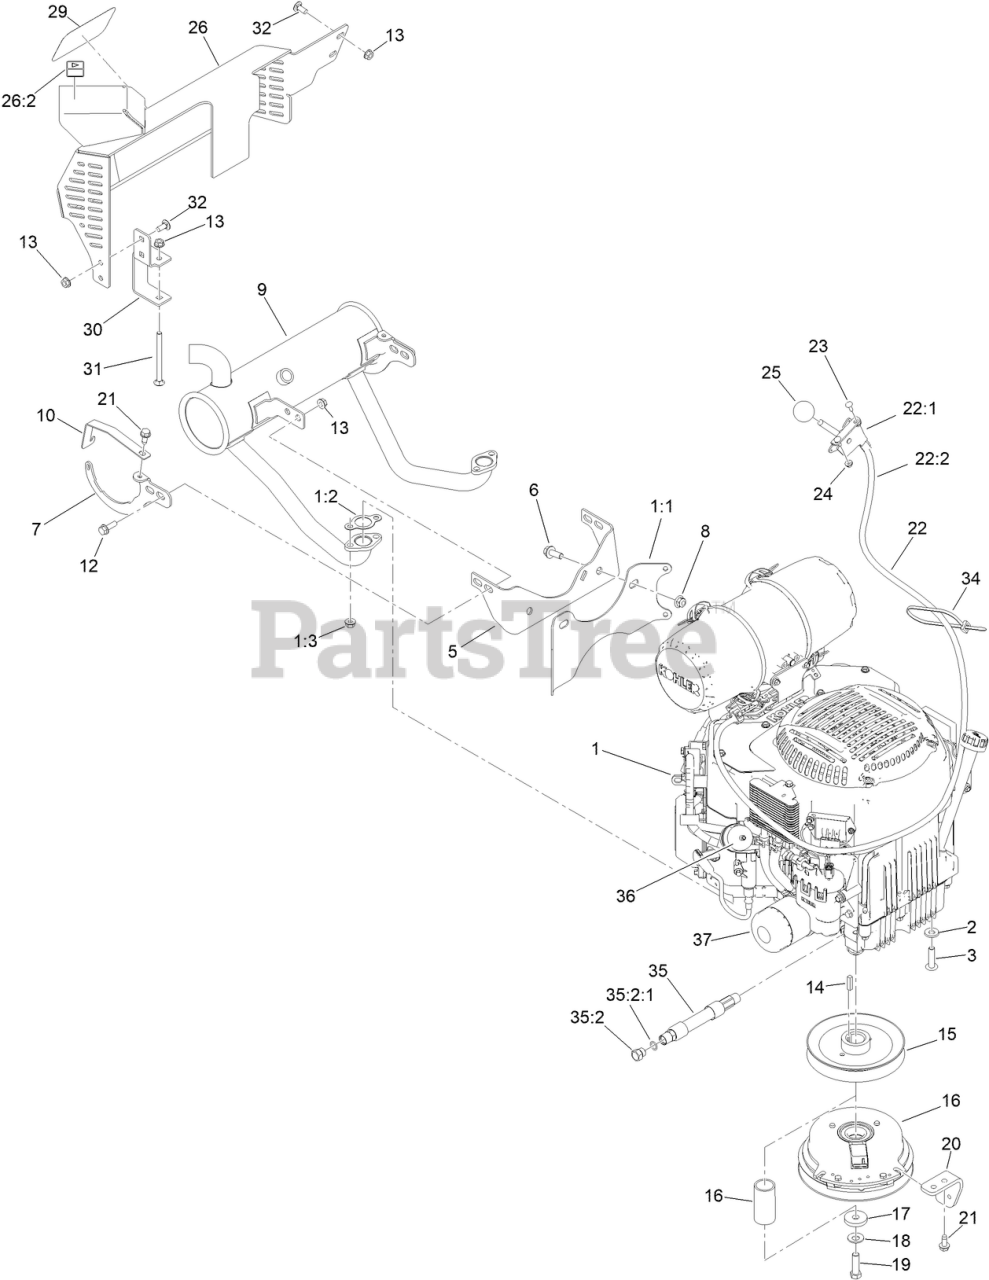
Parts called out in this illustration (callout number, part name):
1:1	BRACKET-MUFFLER
1:2	GASKET-EXHAUST
1:3	NUT-FLANGE
2	WASHER-BELLEVILLE
3	SCREW-BHTF
5	BRACKET-MUFFLER
6	SCREW-HHF
7	SUPPORT-MUFFLER
8	NUT-HF, NI
9	MUFFLER-KOHLER
10	BRACKET-MUFFLER, KOH
12	SCREW-HHF
13	NUT-HF
15	PULLEY
16	CLUTCH-200CMS
17	WASHER
18	WASHER-SPRING
19	SCREW-HH
20	STOP-CLUTCH
21	SCREW-HWHTF
22	THROTTLE ASM
22:1	LEVER-CONTROL
22:2	CABLE - THROTTLE
23	BOLT-CARR
24	NUT-LOCK, FLANGE
25	KNOB-BALL
26	MUFFLER GUARD ASM
26:2	DECAL-WARNING
29	DECAL
30	BRACKET-MOUNTING, GUARD
31	SCREW-CARR
32	SCREW-CARR
34	TIE-CABLE
35	HOSE ASM
35:2	PLUG-HH
35:2:1	O-RING
36	FILTER-FUEL
37	FILTER-OIL
